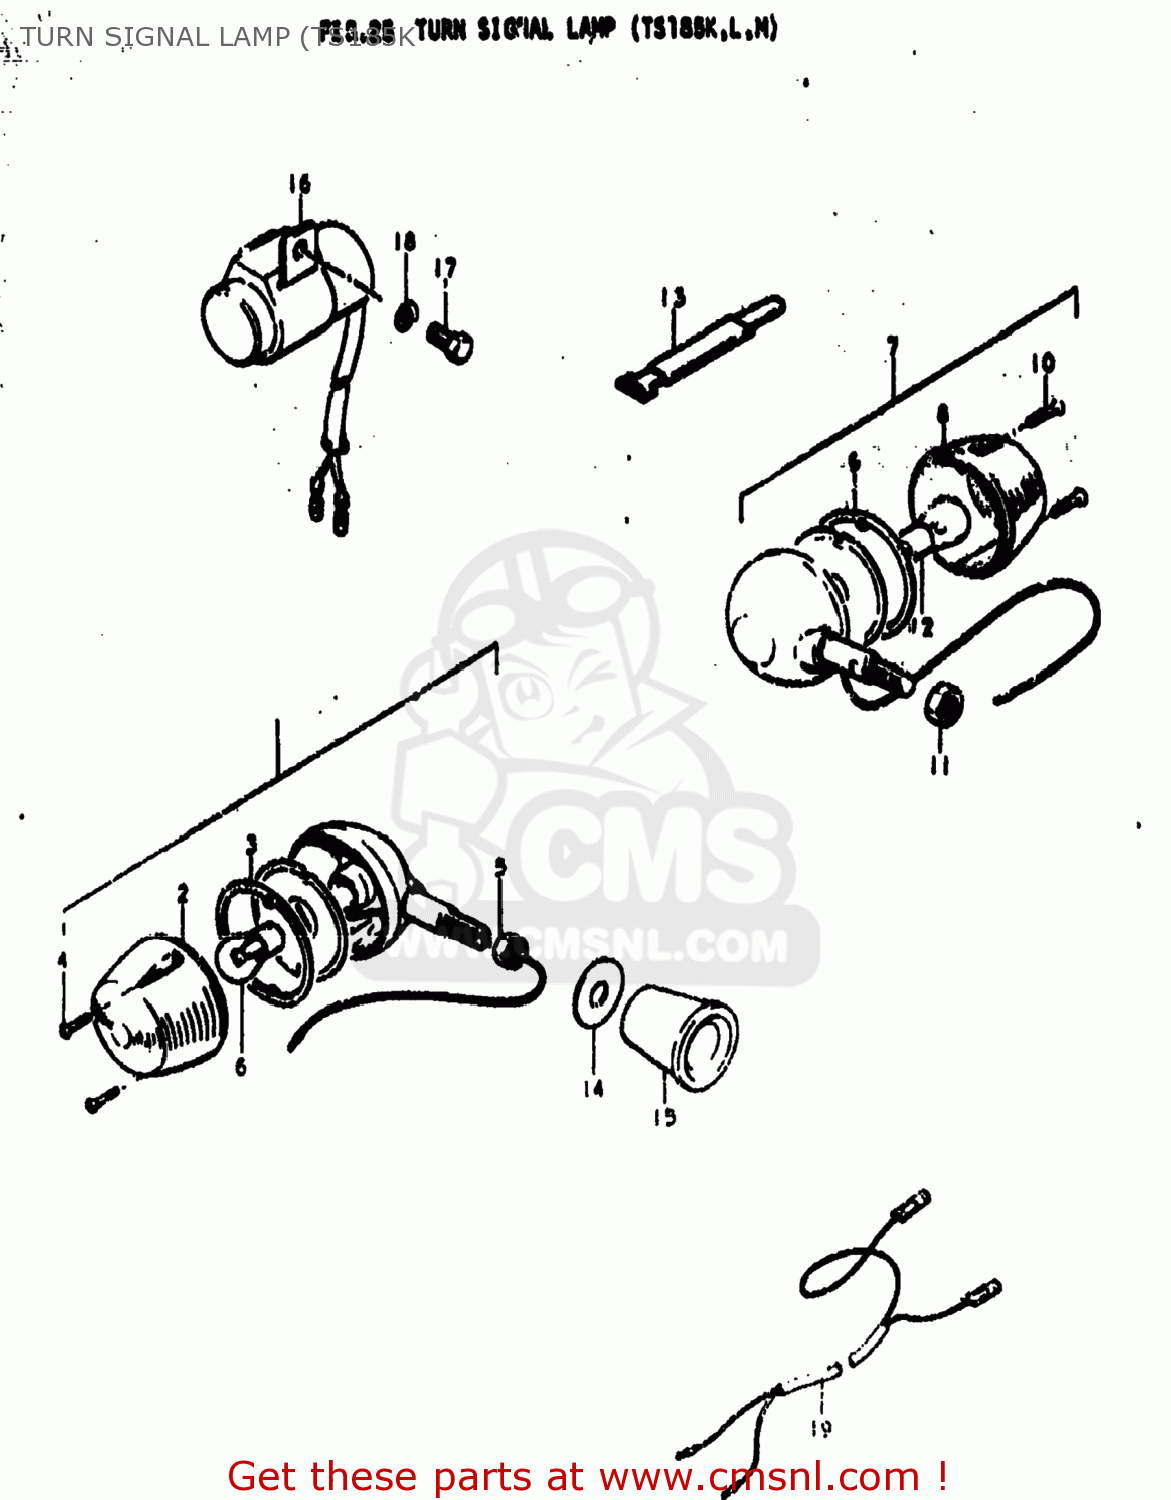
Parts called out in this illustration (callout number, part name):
1	LAMP ASSEMBLY,FRONT TURN SIGNAL
2	LENS,TURNSIGNAL
3	GASKET,TURNSIGNAL LENS (NAS)
4	SCREW
5	NUT
6	BULB(6V17W,STANLEY,A4513A)
7	LAMP ASSEMBLY,REAR TURN SIGNAL
8	LENS,TURNSIGNAL
9	GASKET,TURNSIGNAL LENS (NAS)
10	SCREW
11	NUT
12	BULB(6V17W,STANLEY,A4513A)
13	CLAMP
14	WASHER
15	COVER,FRONT TURN SIGNAL BRACKET
16	RELAY,TURN SIGNAL
17	BOLT
18	LOCK WASHER
19	WIRE,REAR TURN SIGNAL,LEFT
